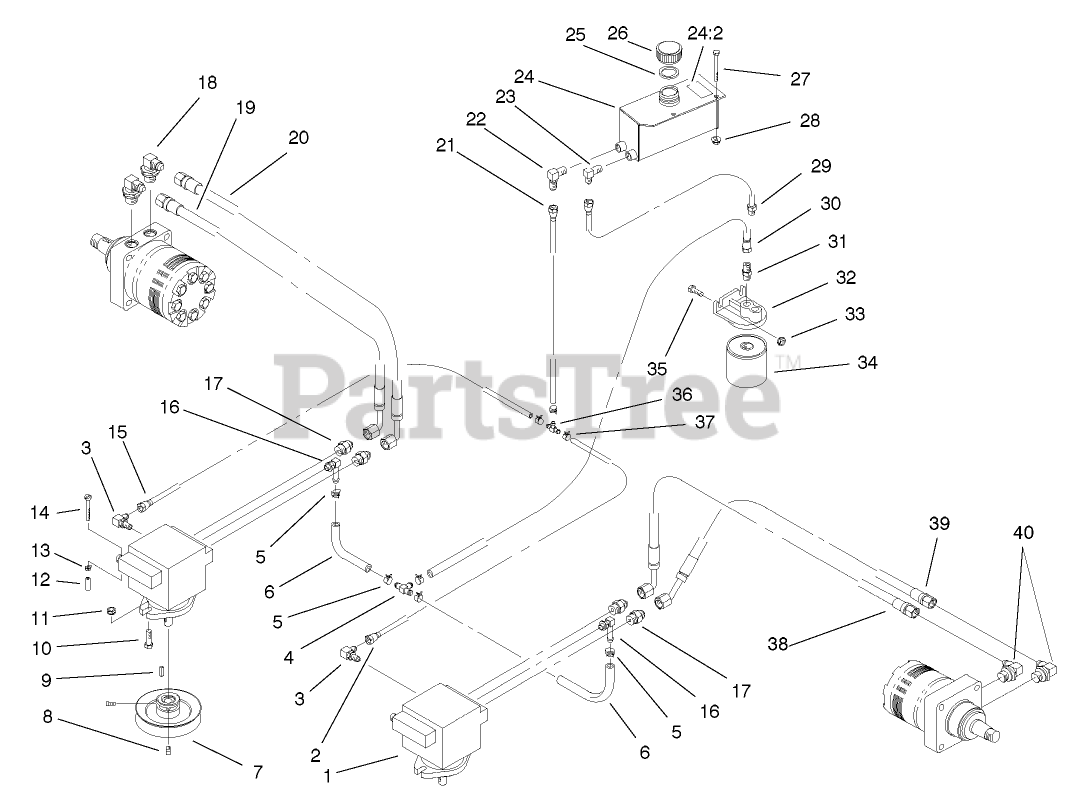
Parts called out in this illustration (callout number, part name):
1	PUMP-HYDRAULIC
2	HOSE ASM
3	FITTING-90 DEG
4	FITTING-TEE, HOSE
5	CLAMP-HOSE
7	SHEAVE ASM
8	SCREW-SET
10	SCREW-HH
11	NUT-HHF, WHIZ
12	GRIP-VALVE, DUMP
13	NUT-LOCK, NI
15	HOSE ASM
16	FITTING
17	FITTING-STRAIGHT
18	FITTING-HYD, 90 DEG
19	HOSE-FRONT
20	HOSE-REAR, RH
22	FITTING-ELBOW
23	FITTING-ELBOW
24	HYDRAULIC TANK ASM
24:2	DECAL-TANK, HYD
25	GASKET-CAP, TANK
27	SCREW-HH
28	NUT-HF
31	FITTING-STRAIGHT
32	HEAD-FILTER
33	NUT-HF
34	FILTER-OIL, HYD
34	FILTER-OIL, HYD (WINTER)
35	SCREW-HH
36	FITTING-TEE, HOSE
37	CLAMP-HOSE
38	HOSE,HYDRAULIC
39	HOSE,HYDRAULIC
40	FITTING-90 DEG
